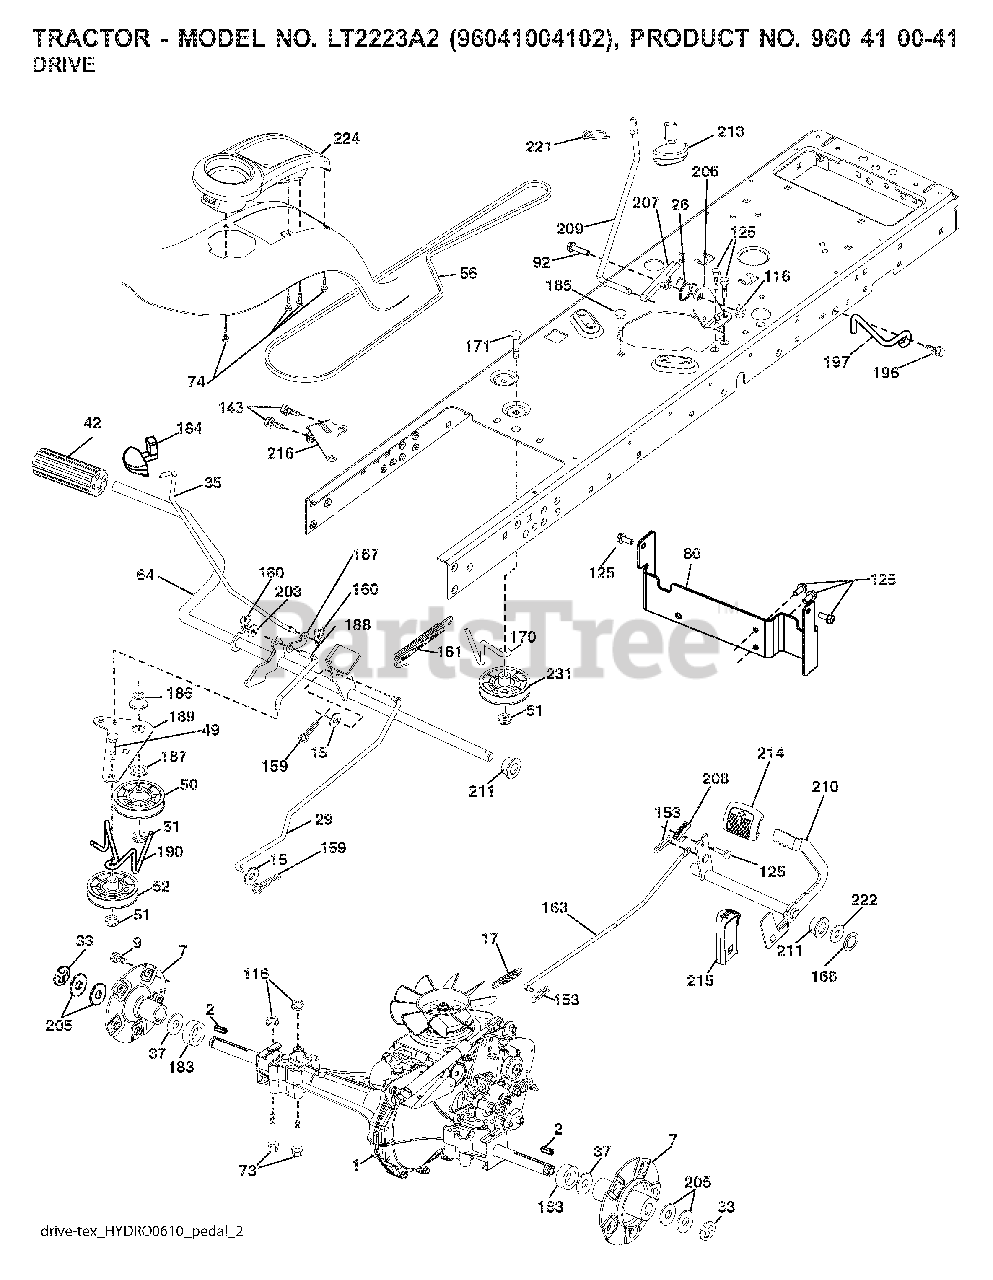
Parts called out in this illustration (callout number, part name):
2	KEY.SQUARE.187X2.500
7	HUB.ASM.WHEEL.REAR.22"
9	HUB BOLT
17	SPRING.BRAKE.HG3000/3500
26	SPRING.RETURN.CRUISE
29	ROD.BRAKE.0610.PEDAL.CONTROL
33	E-RING LT
35	ROD.BRKAE.PARKING.STEALTH
42	PEDAL COVER T
49	BOLT
50	IDLER.FLAT.910.OFFSET
51	NUT LOCK FLG 3/8-16 UNC
52	IDLER.V-GROOVE.910.OFFSET
64	SHAFT.ASM.PEDAL.BRK.CNTR
73	BOLT HEX 5/16-18 GR 5
74	SCREW.HI-LO.CONSOLE
80	BRKT.STRP.TRQ.LT.HYD.C
92	BOLT
116	NUT LOCK HEX FLANGE 5/16-18
125	SCREW
143	SCREW LT
153	RETAINER M
159	COTTER PIN
160	RETAINER CLIP
161	SPRING, RETURN LT
163	ROD.PEDAL.CONTROL.0510
166	NUT.PUSH.625.2006
167	LATCH.BRAKE.SPRING
170	KEEPER.V-IDLER.CENTER.
183	SPACER.SPLIT.800X.350
184	HANDLE.PRKG.BRAKE.STLTH.TX.RED
185	BOLT
186	SPACER.RETAINER
187	WASHER 12/32X2X10GA
188	LINK.CLUTCH.GROUND.DRIVE
189	BELLCRANK.GROUND.DRIVE.TEX.
190	KEEPER.BELLCRANK.DRIVE
196	SCREW 3/8-16X1
197	BRKT.ANIT-ROTATION.CLU
203	WASHER
206	BRKT.MOUNT.LATCH.CRUIS
207	LATCH.CONTROL.CRUISE
208	GEAR.SECTOR.CONTROL.CR
209	ROD.CONTROL.CRUISE.STEALTH.TEX
210	ROCKER.ASM.PEDAL.CONTR
211	BEARING.NYLON
213	KNOB.CONTROL.CRUISE
214	PEDAL.FORWARD.TEX.GT.4
215	PEDAL.REVERSE.TEX.GT.4
216	BRACKET.PULLEY.IDLER.W/TEX
221	RETAINER.SPRING.CLIP.H
222	WASHER 21/32 X 1-1/4 X 10 GA.
224	CONSOLE.TOOLBOX.PCH.ERGO.BLACK
231	IDLER.V-GROOVE.1.688.OFFSET
